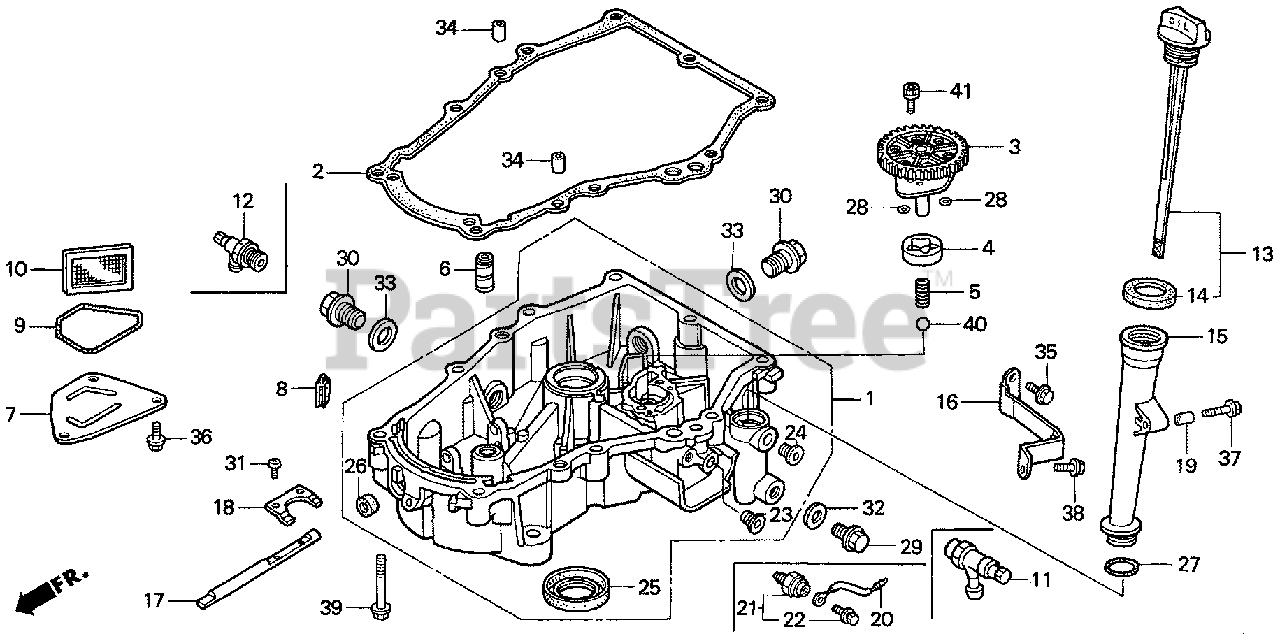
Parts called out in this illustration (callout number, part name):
1	PAN ASSY., OIL
2	GASKET, CASE COVER
3	COVER ASSY., OIL PUMP
4	ROTOR, OIL PUMP (OUTER)
5	SPRING, RELIEF VALVE
6	SHAFT, OIL CONTROL
7	PLATE, OIL FILTER
8	RUBBER, OIL RETURN
9	O-RING, OIL PLATE
10	SCREEN, OIL FILTER
11	VALVE, DRAIN (14X1.5)
12	VALVE, OIL SHUT-OFF
13	CAP ASSY., OIL FILLER
14	GASKET, OIL FILLER CAP
15	EXTENSION, OIL FILLER
16	STAY, OIL FILLER EXTENSION
17	SHAFT, GOVERNOR ARM
18	FORK, GOVERNOR
19	COLLAR, EXTENSION
20	WIRE, OIL PRESSURE SWITCH
21	SWITCH, OIL PRESSURE
22	SCREW-WASHER (4X8)
23	BOLT, SEALING
24	PLUG, SEALING (10MM)
25	OIL SEAL (38X58X11)
26	OIL SEAL (10X20X5)
27	O-RING (22.5X2.2)
28	O-RING (13X3.0)
29	BOLT, DRAIN PLUG (14MM)
30	BOLT, DRAIN PLUG (20MM)
31	SCREW, PAN (5X10)
32	WASHER, DRAIN PLUG (14MM)
33	WASHER, DRAIN PLUG (20MM)
34	PIN A, DOWEL (8X14)
35	BOLT, FLANGE (6X12)
36	BOLT, FLANGE (6X14)
37	BOLT, FLANGE (6X28)
38	BOLT, FLANGE (8X16)
39	BOLT, FLANGE (8X50)
40	BALL, STEEL (#12) (3/8)
41	BOLT, SOCKET (6X16)
